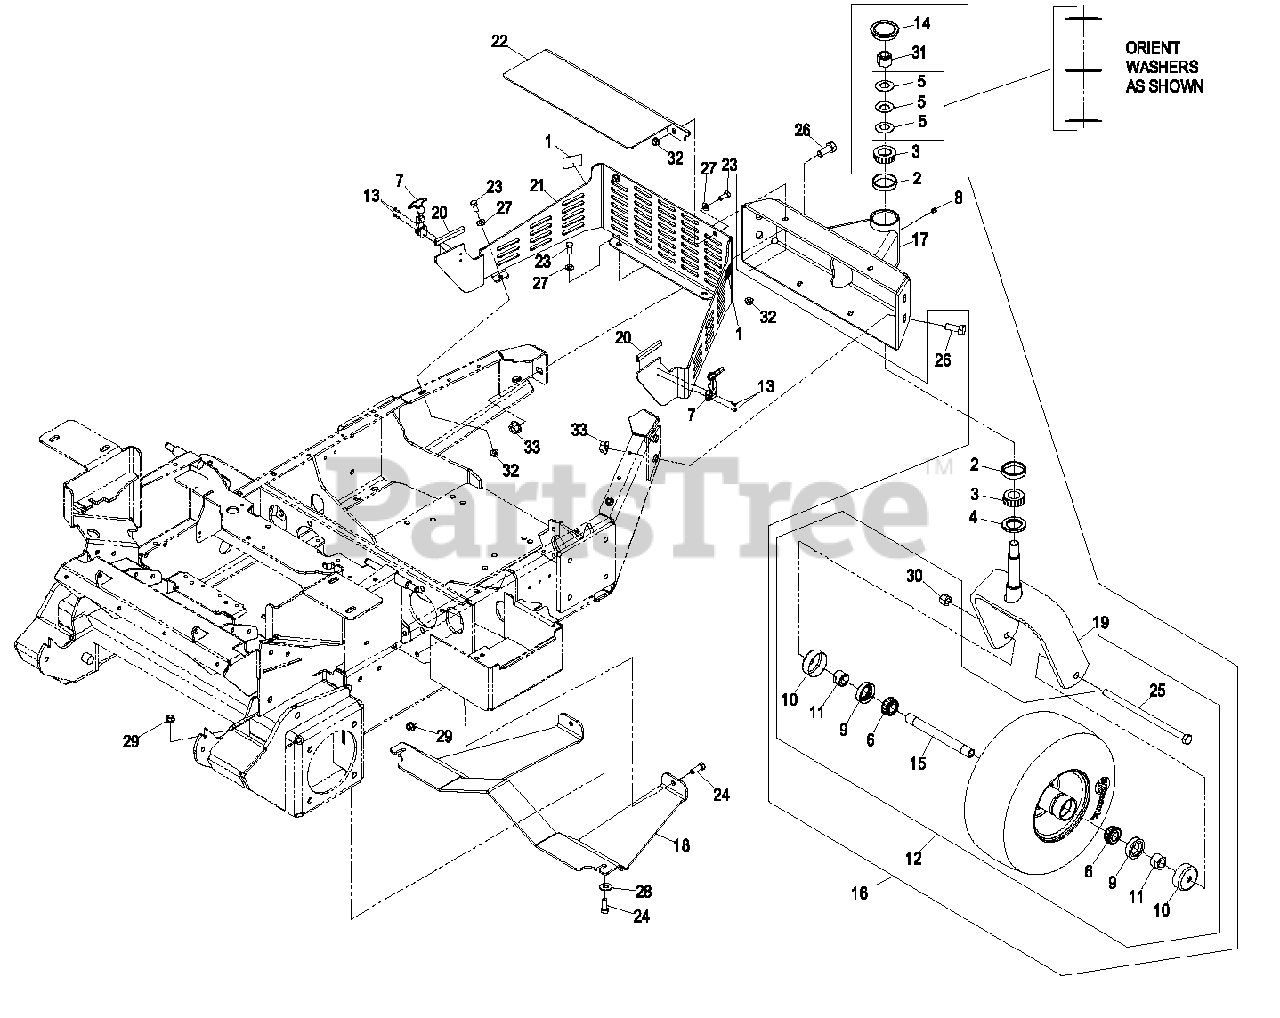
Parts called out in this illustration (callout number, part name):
2	CUP-BEARING
3	Cone-Bearing Tapered Roller
4	SEAL-GREASE
5	WASHER-BELLVILLE
6	BEARING-CONE, TAPERED ROLLER
7	LATCH-RUBBER
9	SEAL-CASTER
10	GUARD-SEAL
11	SPACER-NUT
14	CAP-GREASE
16	ASM,SINGLE TAILWHEEL
20	STRIP-SEAL
21	ASM,FMZ REAR GUARD
22	COVER,MUFFLER FMZ
23	SCREW-HH
24	SCREW-HH
25	SCREW-HH
26	SCREW-HH
27	WASHER-PLAIN
28	WASHER-FLAT
29	NUT-HHF, WHIZ
30	NUT-LOCK, NI
31	NUT-LOCK, NI
33	NUT-HHF
